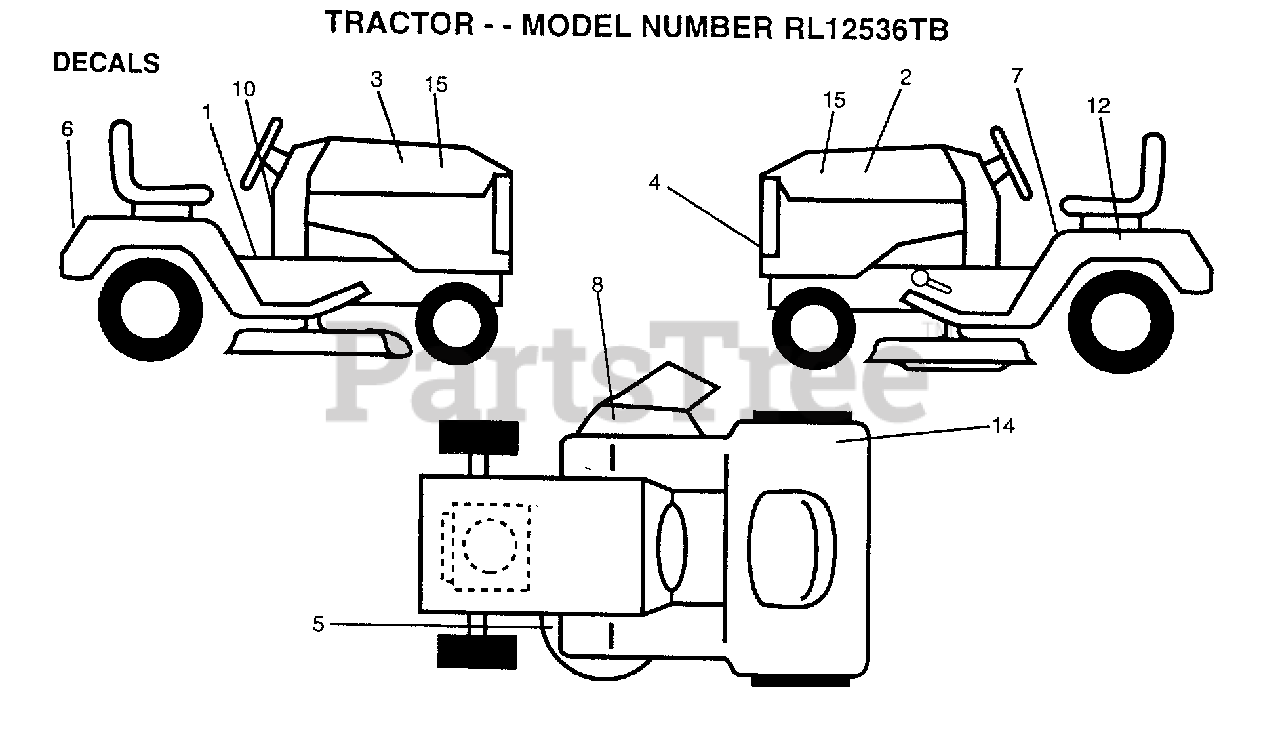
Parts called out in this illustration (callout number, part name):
1	DECAL.OP.INST.SYM
2	DECAL HD RLY LH
3	DECAL HD RLY RH
4	GRILL DECAL
5	DECAL.V.BELT
6	FENDER DECAL
7	DECAL.READ.O.MANU
8	DECAL.DANGER.CUTF
10	DECAL.EURO.ST.CE.
12	DECAL.BTRY.DANGER
15	DECAL.INS.HD.12.5
